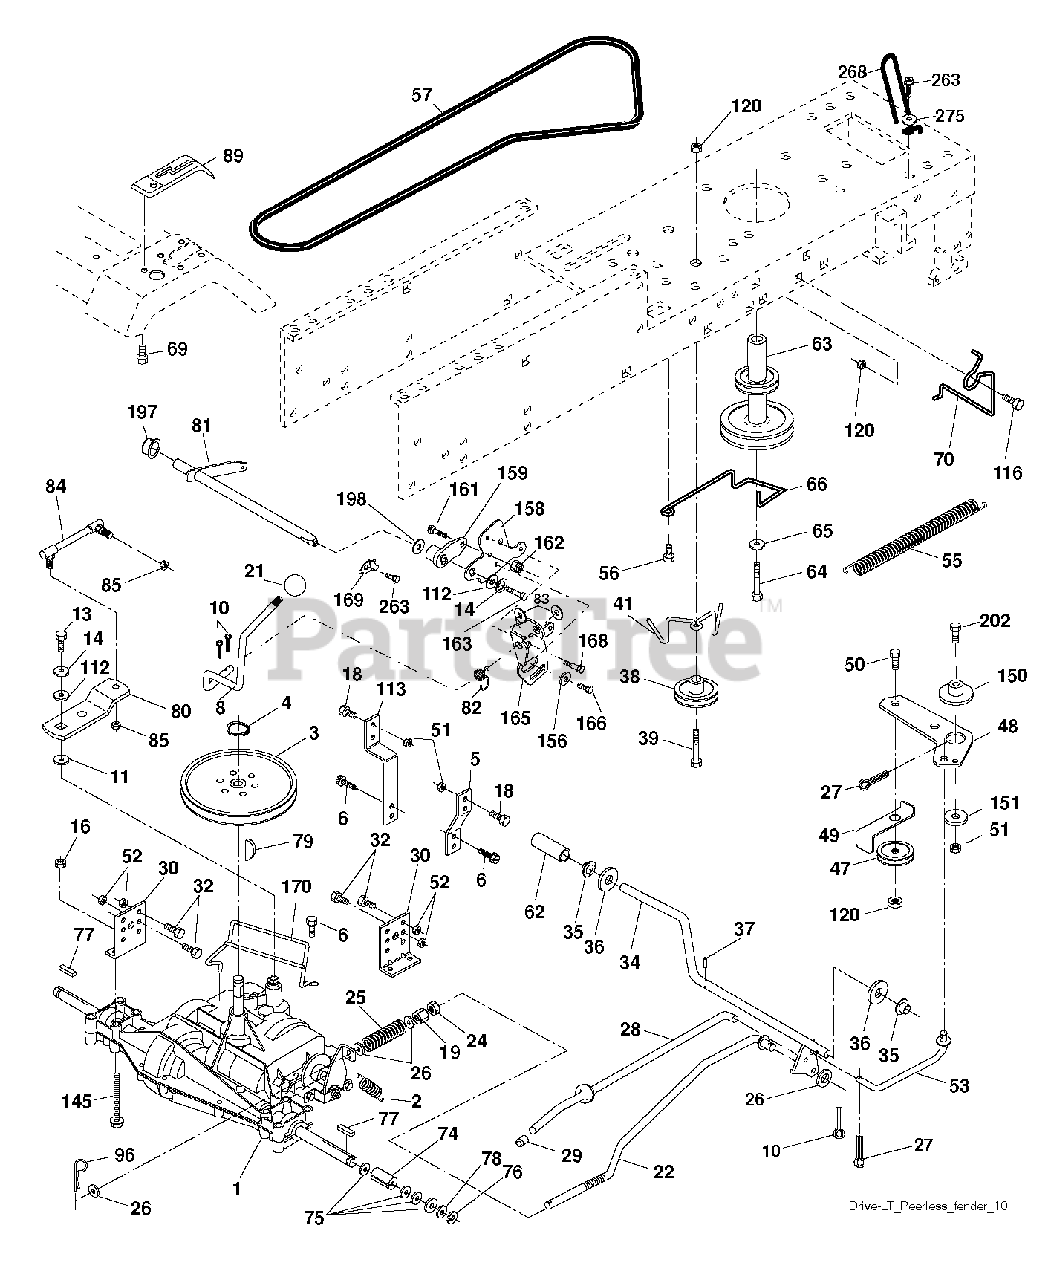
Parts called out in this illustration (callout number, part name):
2	SPRING,BRAKE RETURN
3	PULLEY TRANS
4	RETAINING RING LT
5	STRAP TORQUE
6	SCREW 5/16"
8	ROD SHIFT FENDER ADJUST LT
10	PIN COTTER
11	WASH-SHFT PLT LT
13	Bolt, 1/4-20 unf Grade 8 w/Patch
14	LOCKWASHER
16	NUT.71038.31-18.HEX.NYLOCK
19	NUT
21	KNOB T (1/2-HOLE)
22	ROD BRAKE
24	NUT
25	SPRING ROD LT
27	COTTER PIN
28	ROD, PARKING BRAKE
29	PLUNGER CAP
32	BOLT
34	SHAFT, FOOT PEDAL
35	BEARING.NYLON
36	WASHER LT
38	PULLEY IDLER COMPOSITE
41	KEEPER, BELT IDLER
47	Idler Pulley
48	BELLCRANK, CLUTCH
49	RETAIN BELT
50	BOLT.3/8-16X1.50
51	LOCKNUT
52	LOCKNUT
53	LINK.CLUTCH.7.66.2005
55	SPRING, RETURN LT
56	SCREW.3/8-16
57	BELT, V GROUND DRIVE 95 25
63	ENGINE PULLEY
64	BOLT HEX 7/16-20X4-1/4"
65	LOCKWASHER
66	KEEPER BELT ENGINE
69	SCREW.HI-LO.CONSOLE
70	KEEPER BELT ENG
74	SPACER AXLE
76	E-RING LT
77	SQUARE KEY
79	KEY STD (1373) DANA
80	ARM SHIFT
81	SHAFT ASM CROSS TAPERED
82	SHIFT SPRING
83	WASHER
84	LINK.TRNSAXLE
85	NUT LOCK CENTER 1/4 -28 FNTHD
89	CONSOLE SHIFT STLT
112	WASHER LT
113	STRAP TORQUE LH LT
120	NUT LOCK FLG 3/8-16 UNC
150	SPACER, RETAINER
151	WASHER 12/32X2X10GA
156	WASHER.SRRTD.5/16
158	BRACKET.SHIFT.MOUNT
159	HUB.SHIFT
161	BOLT
162	NUT.CROWNLOCK.1/4
165	BRACKET.PIVOT.LEVER
168	BOLT.SHOULDER.5/16-18X
169	PLATE FASTENING LT
170	KEEPER BELT T/A
197	NYLINER SNAP 5/8" ID
198	WASHER NYL
202	BOLT
263	SCREW, 3/8-16X3/4
